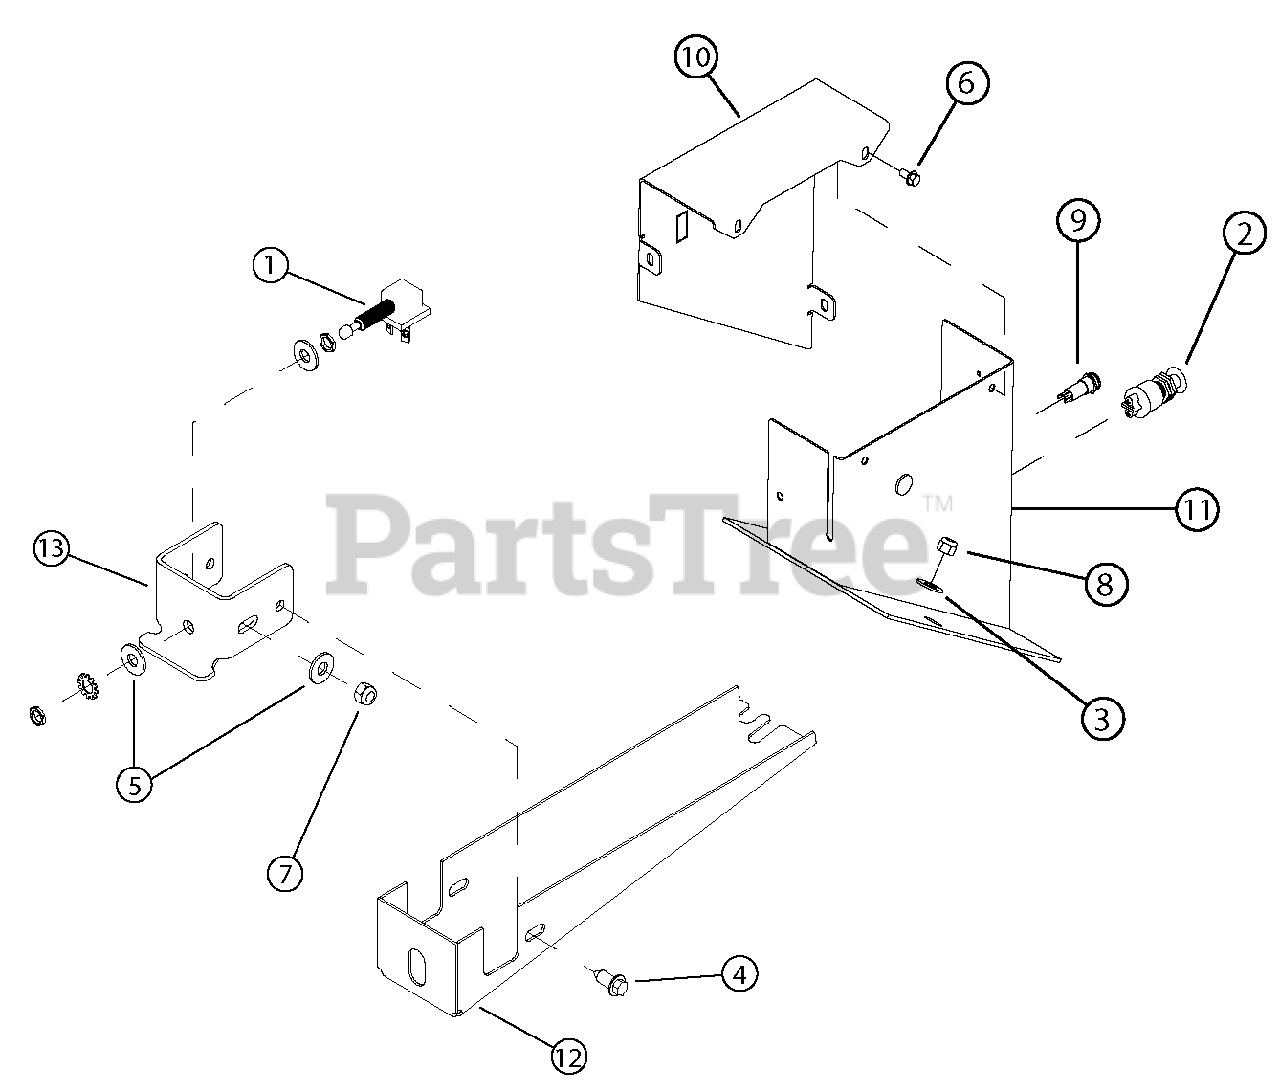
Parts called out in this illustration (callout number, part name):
1	SWITCH, N/C MOMENTATY PLUNGER
2	SWITCH, N/O MOMENTARY PUSHBUTTON
3	WASHER, 3/8 FLAT
4	SCREW, 11/32 X 7/8 HWH AB THREAD
5	WASHER, 5/16 FLAT
6	BOLT, SERR. FLANGE 1/4 X 1/2
7	NUT, 5/16 NYLOCK
8	NUT, 3/8 NYLOCK
9	LED, TRI-COLOR 12V 3-TERM BASE
10	PLATE, CONTROL BOX
11	WELDMENT, SWITCH MOUNT
12	SHIELD, KNEEBAR SWITCH
13	BRACKET, SWITCH
